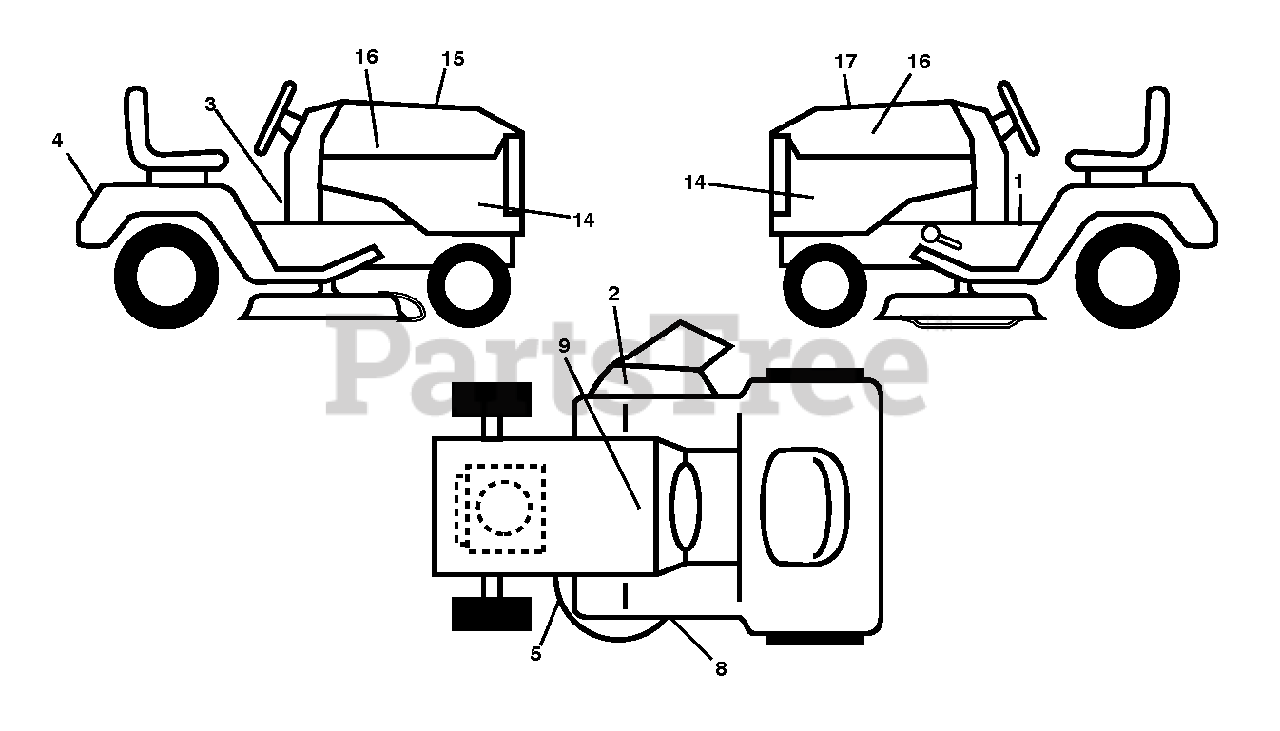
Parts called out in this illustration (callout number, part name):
1	DECAL.FENDER.WARNING
2	DECAL.WARN.KEEP.HAND.AWAY
3	DECAL, WARNING SPARK ARRESTOR
4	DECAL.FENDER
5	DECAL.MOWER
8	DECAL.MOWER.SCH.48/54
9	DECAL BTRY SYMBOLS
14	DECAL.SIDE.PANEL.YTH24K48
15	DECAL.WARNING.CUST.RESP.E85.
16	RP.DECAL.BADGE.170MM.TEXTLOGO
17	Decal, Replacement YTH24K48
